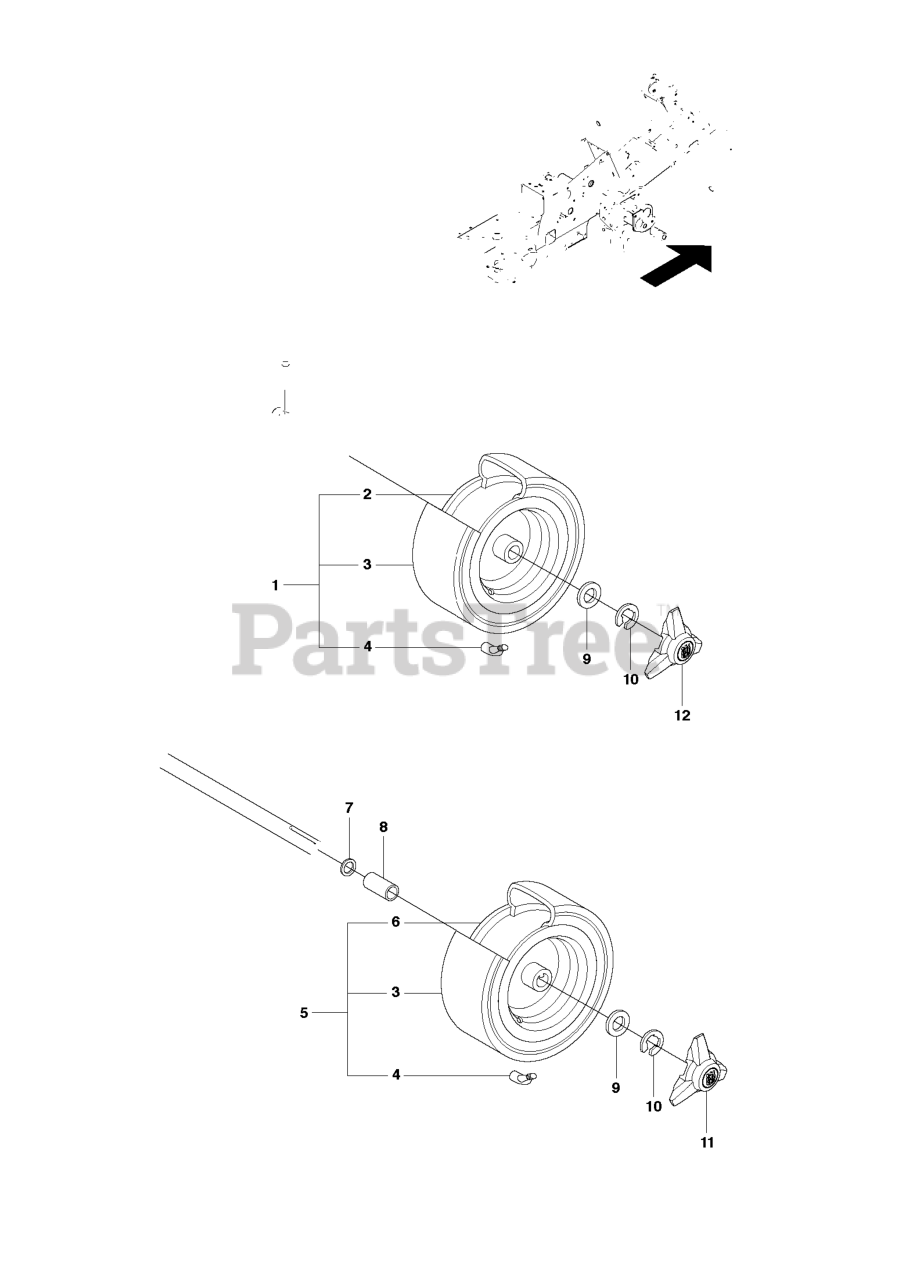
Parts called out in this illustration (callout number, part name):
3	TIRE
4	VALVE
8	SPACE SLEEVE
10	RETAINING RING
